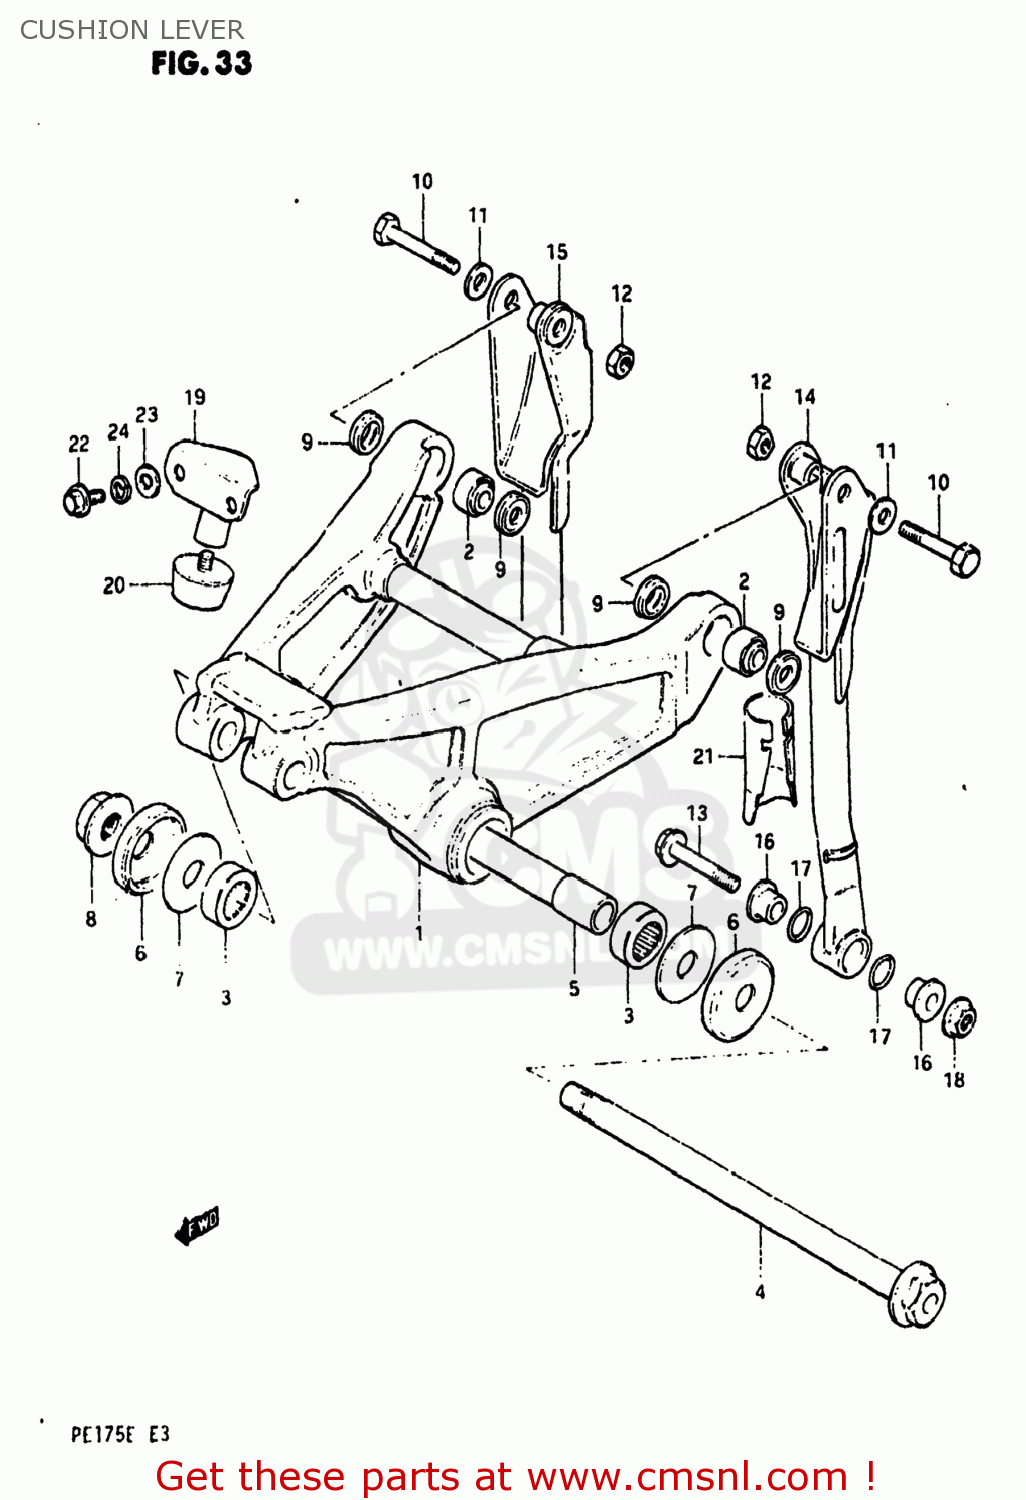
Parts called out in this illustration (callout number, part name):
1	LEVER SET,REAR CUSHION
2	BEARING(8X18X11)
3	BEARING(17X26X20)
4	SHAFT,REAR CUSHION LEVER
5	SPACER,REAR CUSHION LEVER
6	DUST SEAL,REAR CUSHION,LEFT
7	WASHER
8	NUT 12MM
9	DUST SEAL,RR CUSHION LOD UPR.
10	BOLT 8X38
11	WASHER
12	NUT 8MM
13	BOLT(8X45)
14	ROD,REAR CUSHION LEVER,LEFT
15	ROD,REAR CUSHION LEVER,RIGHT
16	SPACER,RR CUSHION ROD LWR
17	DUST SEAL,RR CUSHION LOD LWR
18	NUT
19	STOPPER,TENSION
20	RUBBER,TENSION STOPPER
21	PROTECTOR,REAR CUSHION R
22	BOLT
23	WASHER
24	LOCK WASHER
